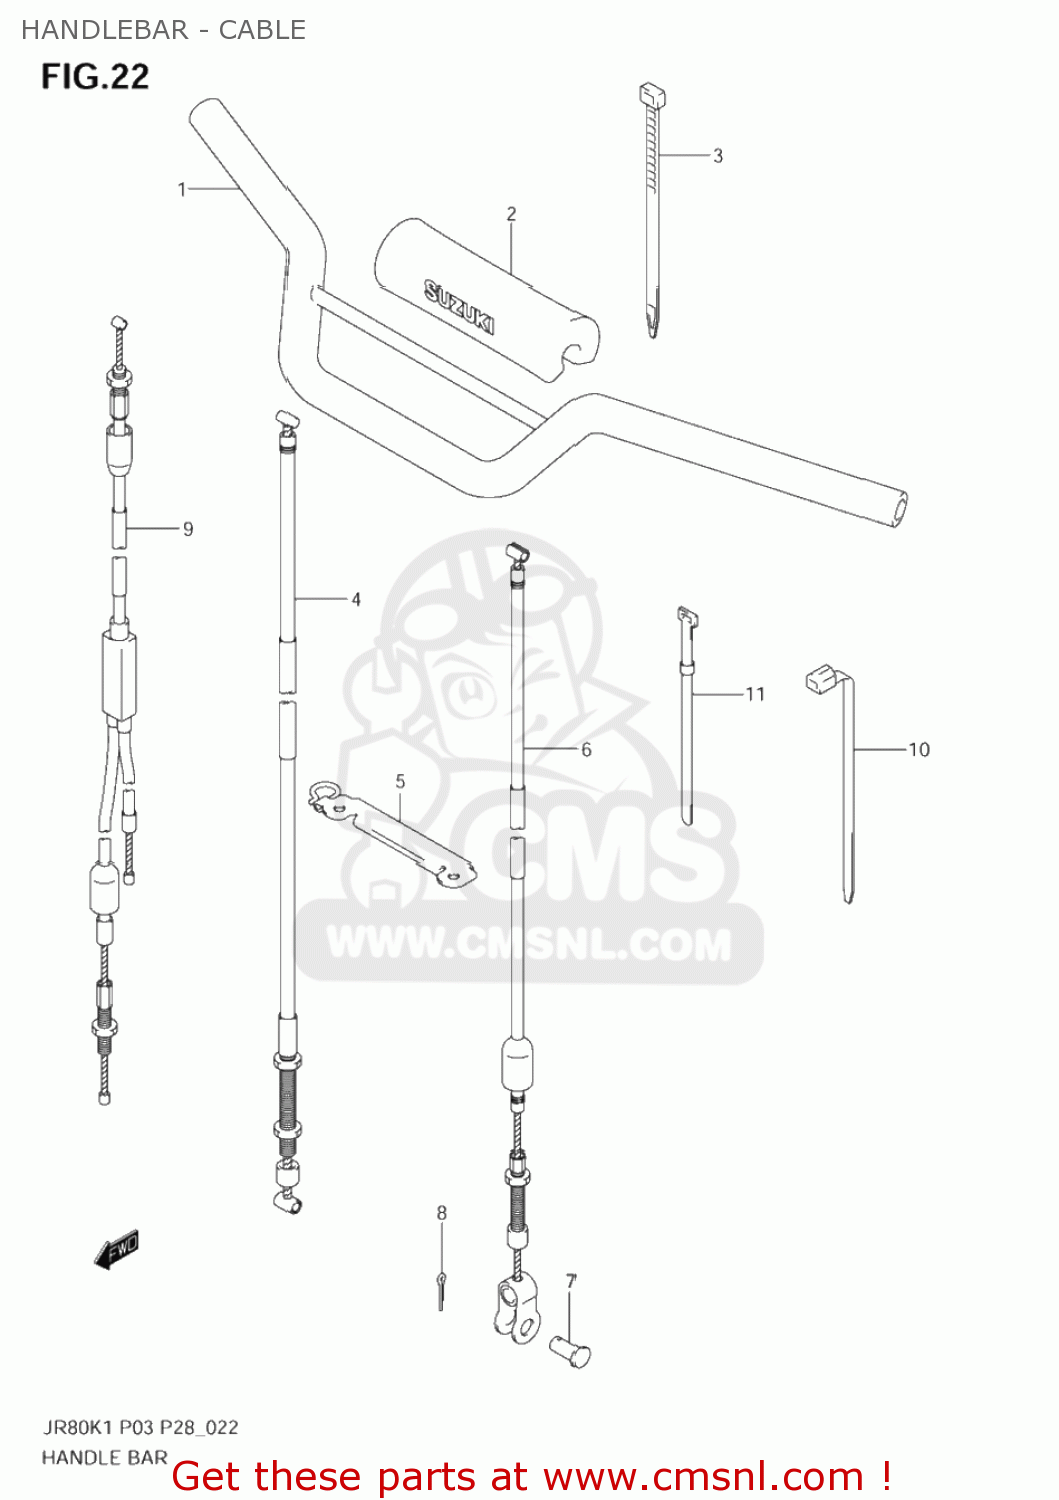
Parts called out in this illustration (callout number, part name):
1	HANDLEBAR(BLACK)
2	PAD,CROSSBAR
3	CLAMP(L:145)
4	CABLE,FR BRAKE
5	GUIDE,FR BRAKE CABLE
6	CABLE ASSY,CLUTCH
7	PIN(L:13)
8	PIN
9	CABLE ASSY,THROTTLE
10	CLAMP(L:125)
11	CLAMP(L:165)
